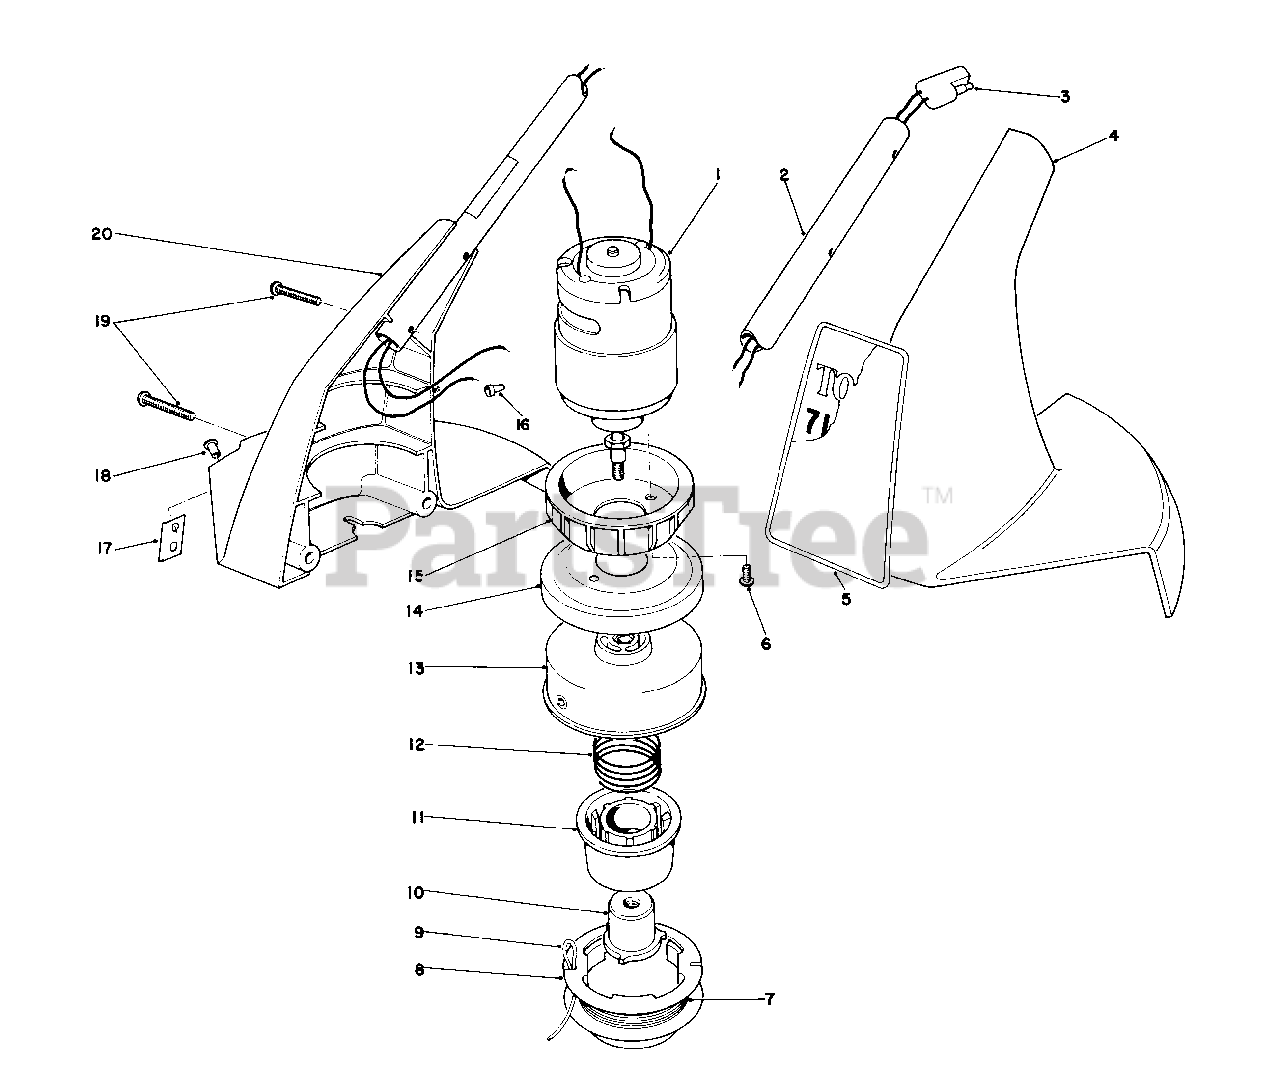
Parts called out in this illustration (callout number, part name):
3	Wiring Harness-Lower
4	Housing-Motor L.H.
5	Decal-Cordless
7	12' .050" Dia. Cutting Line Prewound on Spool
8	Spool-Empty
9	30' .050" Dia. Cutting Line in Coil
12	Spring
13	Drum w/Eyelet
14	Cup-Drum
15	Casting-Heat Sink
16	Connector-Wire
17	Blade-Knife
18	Rivet
20	Housing-R.H. Motor (Incl. Ref. #17 & 18)
